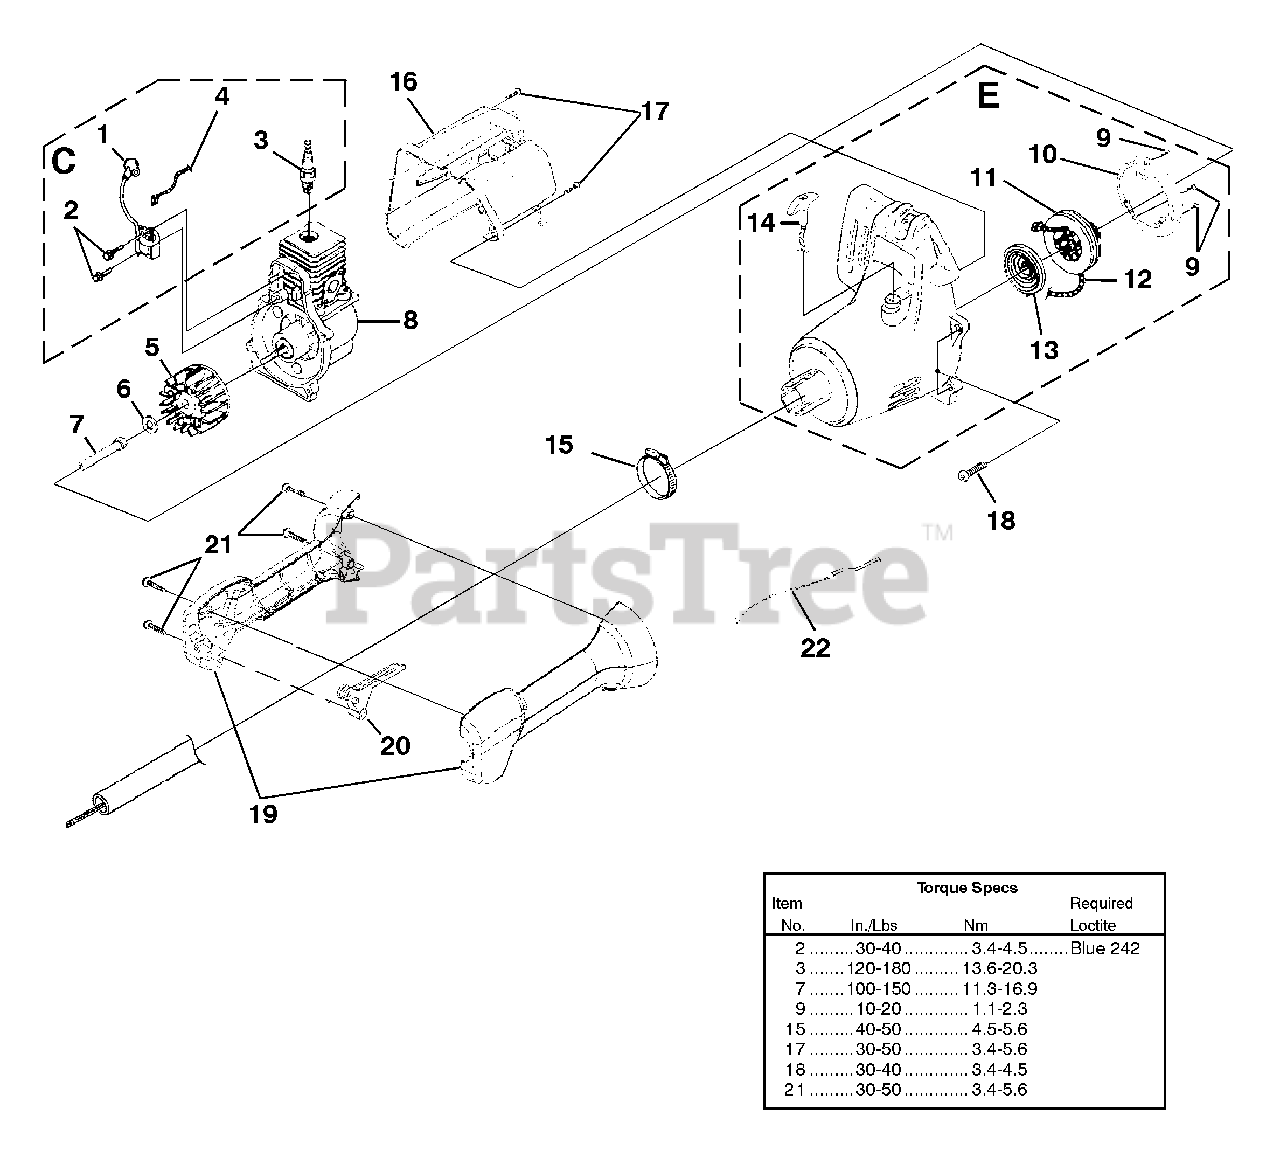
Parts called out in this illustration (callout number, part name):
1	IGNITION MODULE
2	SCREW-Taptite (8-32 X 1")
3	SPARK PLUG
4	LEAD-Electrical
5	ROTOR KIT
6	WASHER-Flat
7	CONNECTOR-Drive (.250)
8	SHORT BLOCK (See Engine Internal)
9	SCREW-Taptite(8-16 X 1/2")
10	BAFFLE-Air
11	PULLEY-Starter
12	ROPE-Starter (42")
13	SPRING & CONTAINER
14	GRIP-Starter
15	CLAMP
16	HOUSING-Rear Engine
17	SCREW-Taptite (10-14 X 7/8")
18	SCREW-Taptite (10-24 X 3/4")
19	CONTROL HANDLE ASSY.
20	TRIGGER-Throttle
21	SCREW-Taptite (10-14 X 7/8")
22	CABLE-Throttle
C	IGNITION KIT
E	COMPLETE STARTER ASSEMBLY
